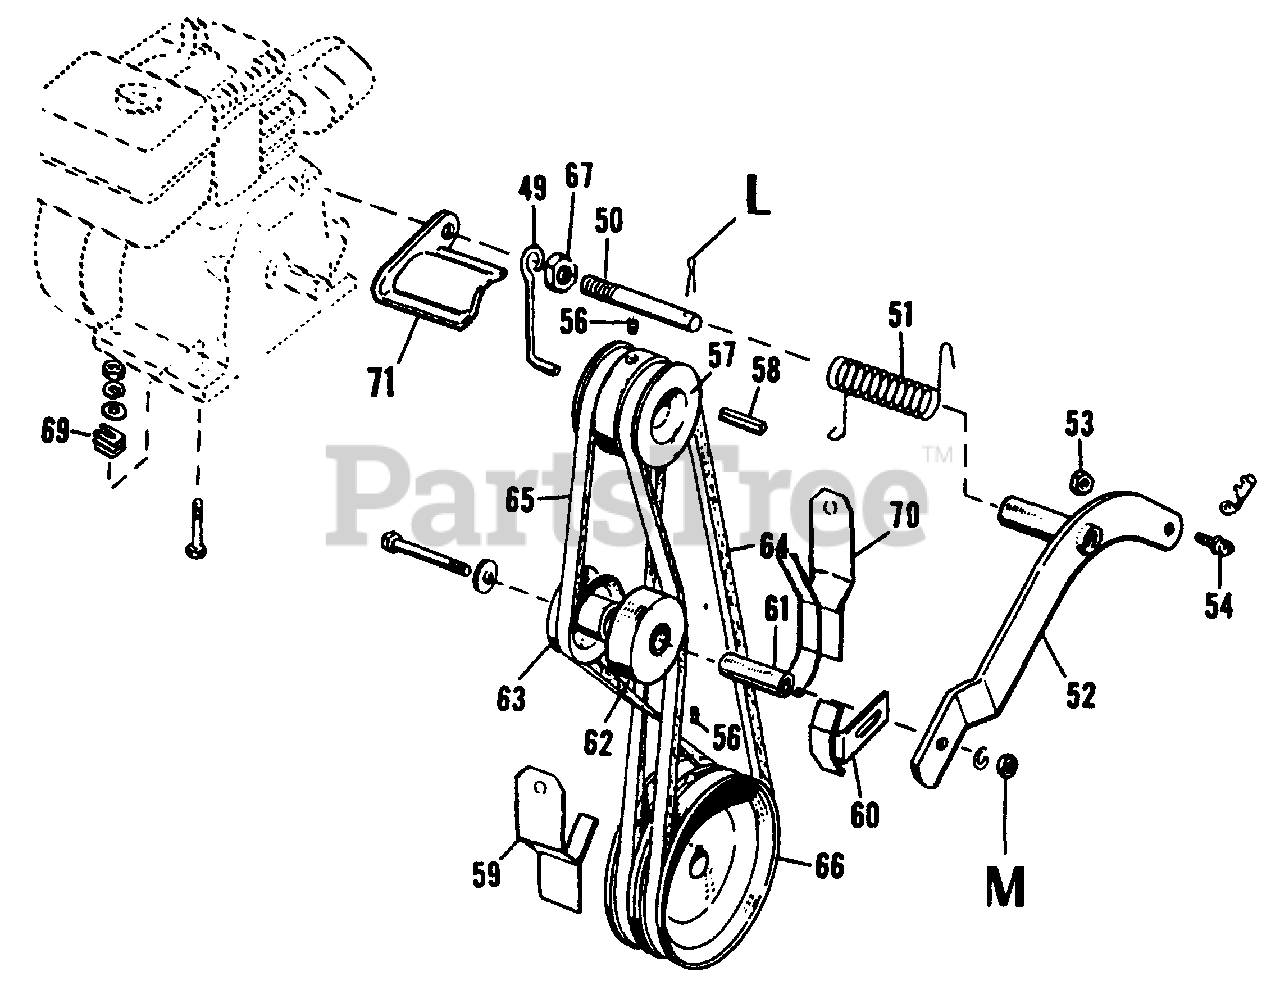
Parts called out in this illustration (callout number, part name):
49	Belt Stop
50	Stud, Engine
51	Spring, Idler Lever
52	Lever Assembly, Idler
53	Hex Nut, Full Lock, 1/4-20 NC
54	Screw, Eye
55	Clip, Rod Clevis
56	Set Screw, Hex Socket, Cup Point, 5/16-18
57	Drive Pulley
59	Belt Guard
60	Belt Retainer
62	Pulley Assembly, Idler
63	Pulley Assembly, Idler Reverse
64	"V" Belt, Forward
65	"V" Belt, Reverse
66	Pulley, Driven
67	Hex Nut, Jam, 1/2-20 NF
70	Guard Assembly, Reverse Belt
71	Guard Belt
